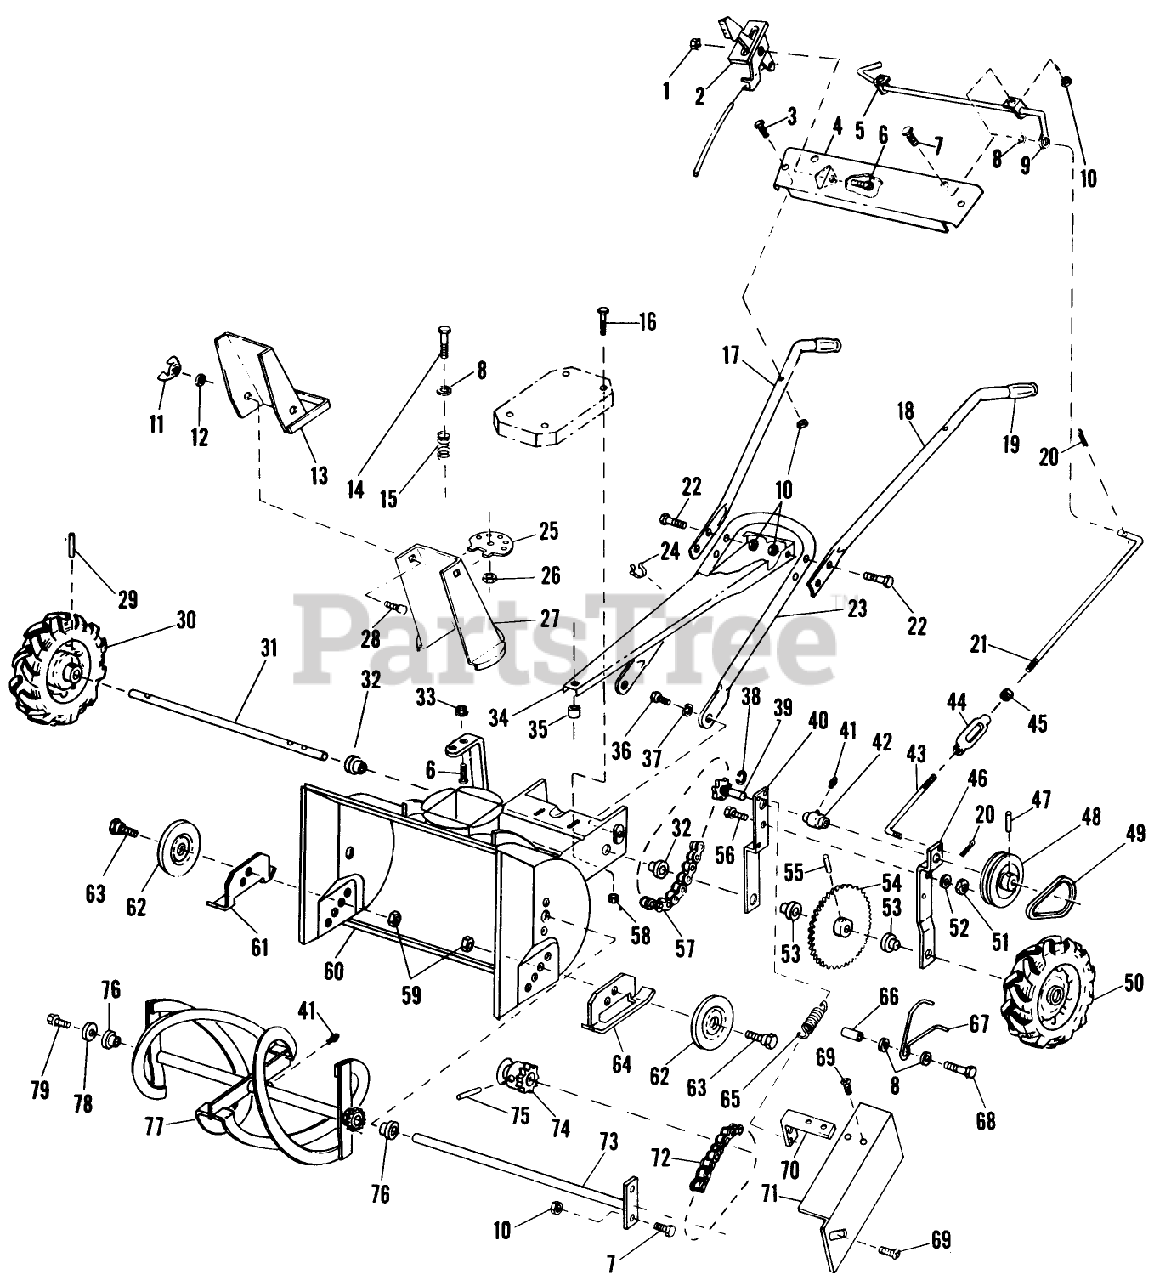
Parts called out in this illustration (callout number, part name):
1	Nut 1/4-20 Keps
2	Control Ass-y. w/Cable
3	Bolt-Carriage 1/4-20-1 1/4
4	Brace-Control
5	Bracket-Clutch Control
6	Screw-Pan Hd. 1/4-20
7	Bolt, 1/4-x 1/2
8	Washer
10	Nut-Nylok
11	Nut, 1/4-20
12	Lockwasher
13	Top Chute Ass-y.
14	Bolt Hex 1/4-20 x 1 3/4
15	Spring-Chute Tension
16	Bolt 5/16-18 x 1/2
17	Handle-Right Hand
18	Handle-Left Hand
19	Grip-Handle
20	Cotter Pin
21	Rod-Clutch Control-Upper
22	Bolt 1/4-20 x 1 1/2
24	Clip-Control Cable
25	Plate-Chute Adjusting
26	Nut-Hex Flange Lock 1/4-20
27	Body-Chute Ass-y.
28	Bolt-Carriage 1/4-20 x 3/4
29	Pin-Spirol 1/4 x 1 1/4
30	Wheel Ass-y. R.H.-10 x 2.75
31	Axle-Snow Thrower
32	Bushing-Axle
33	Nut 1/4-20 Keps
34	Bracket-Yoke Support
35	Spacer-Handle Brace
36	Bolt Hex 3/8 16 x 1/2
37	Washer-Lock 3/8
39	Sprocket-Idler Pulley Shaft
40	Arm-Drive Sprocket Inner
41	Cover-Rubber
43	Rod-Clutch Lower
44	Turnbuckle
45	Nut-Nylok
46	Spring Tension
47	SPIROL PIN
50	Wheel Ass-y. L.H.-10 x 2.75
51	Nut-Nylok
52	Lockwasher
53	Bushing-Drive Sprocket
54	Sprocket-Drive
56	Bolt 5/16-18 x 1
57	Chain w/Master Link
58	Nut 5/16-18 Keps
60	Body Ass-y.-Snow Thrower
61	Foot-Slide R.H.
62	Wheel-Front Adjusting
63	Screw-Hex Shoulder
64	Foot-Slide L.H.
66	Spacer-Belt Guide
67	Guide-Belt
68	Bolt 1/4-20 x 2 1/4
69	Screw Hex-Self-Tapping 8-32 x 3/8"
71	Cover-Belt Guard
72	Chain-w/Master Link
73	Shaft Ass-y.
74	Sprocket Ass-y.
77	Auger Ass-y.
78	Washer-Flat-.327ID x 1 1/8 OD
79	Screw 5/16-18 x 3/4 S.T.
